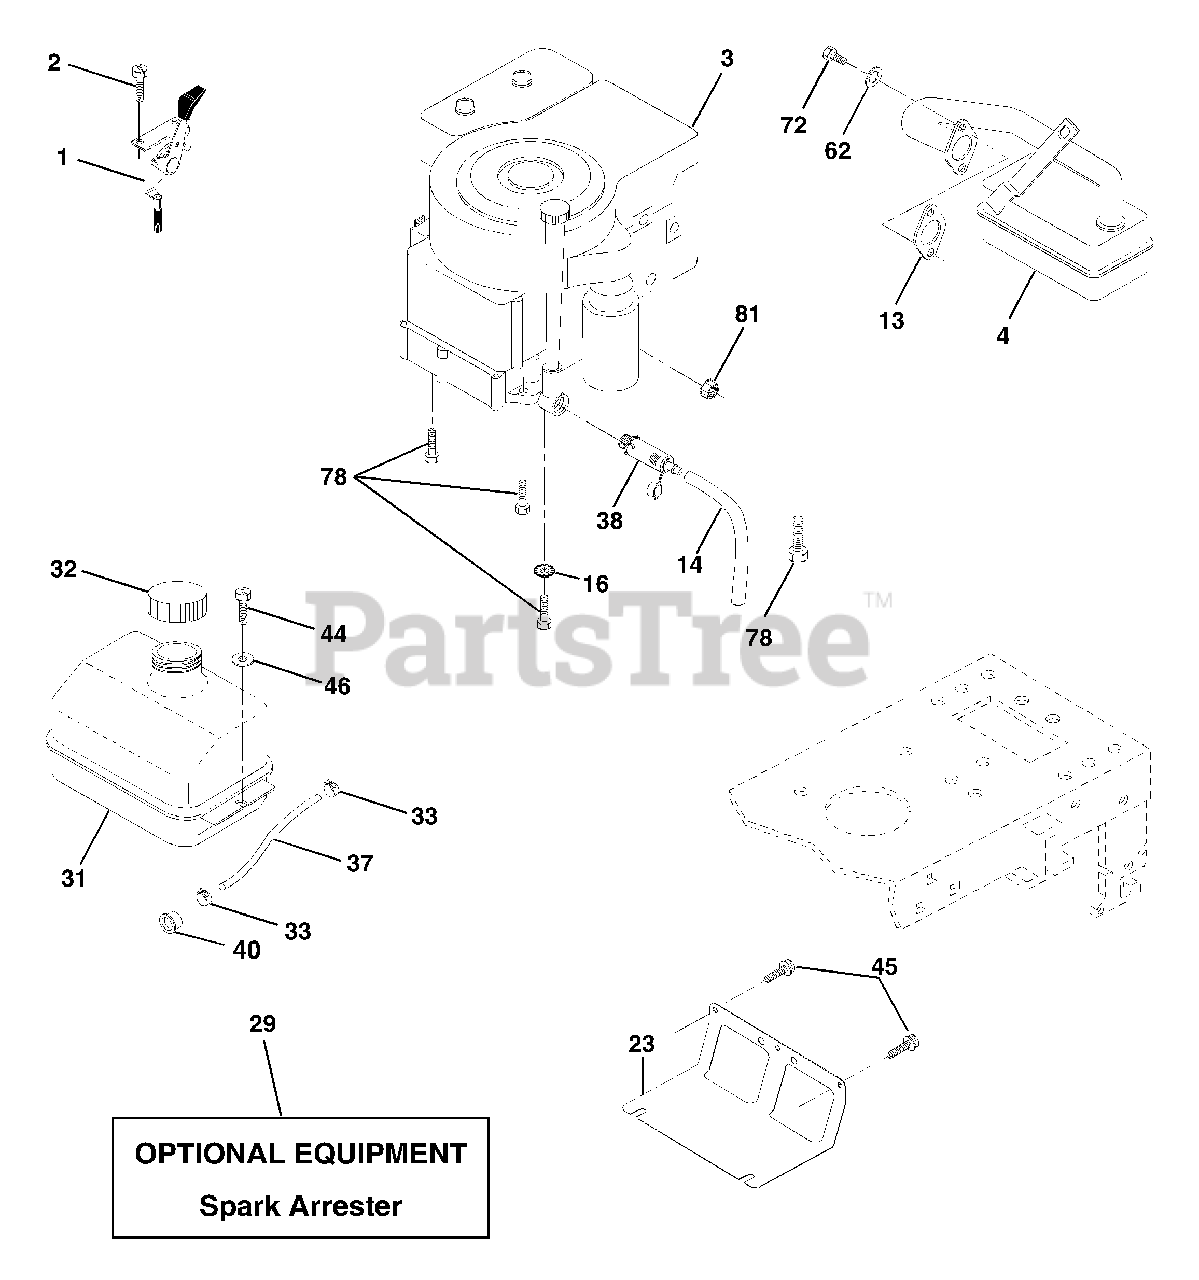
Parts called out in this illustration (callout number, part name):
1	Control Throt /Ch Flag
2	Screw Hex Thd Cut 1/4-20x1/2
4	Muffler Exhaust B&S Lt
13	Gasket 1 313 Id Tin Plated
14	Tube Drain Oil Easy
15	Elbow STD 90 Degree 3/8-18 NPT
16	Washer Lock Ext Tooth 3/8
23	Shield Browning/Debris Guard
29	Arrestor Spark
31	Tank Fuel 1 25 Fr
32	Cap Asm Fuel W/sym Vented
33	Clamp Hose Blk
37	Line Fuel 20"
38	Plug Drain Oil Easy
40	Bushing Snap Nyl Blk Fuel Line
44	Screw Hexwsh Thdrol 1/4-20x3/4
45	Screw Hex Wsh Thdrol 3/8-16
46	Washer 9/32 X 7/8 X 16ga
62	Washer Lock Hvy Hlcl Spr 5/16
72	Screw Hexhd Cap 5/16-18x3/4
78	Screw 3/8-16x1-1/4
81	Nut Keps Hex 1/4-20 Unc
